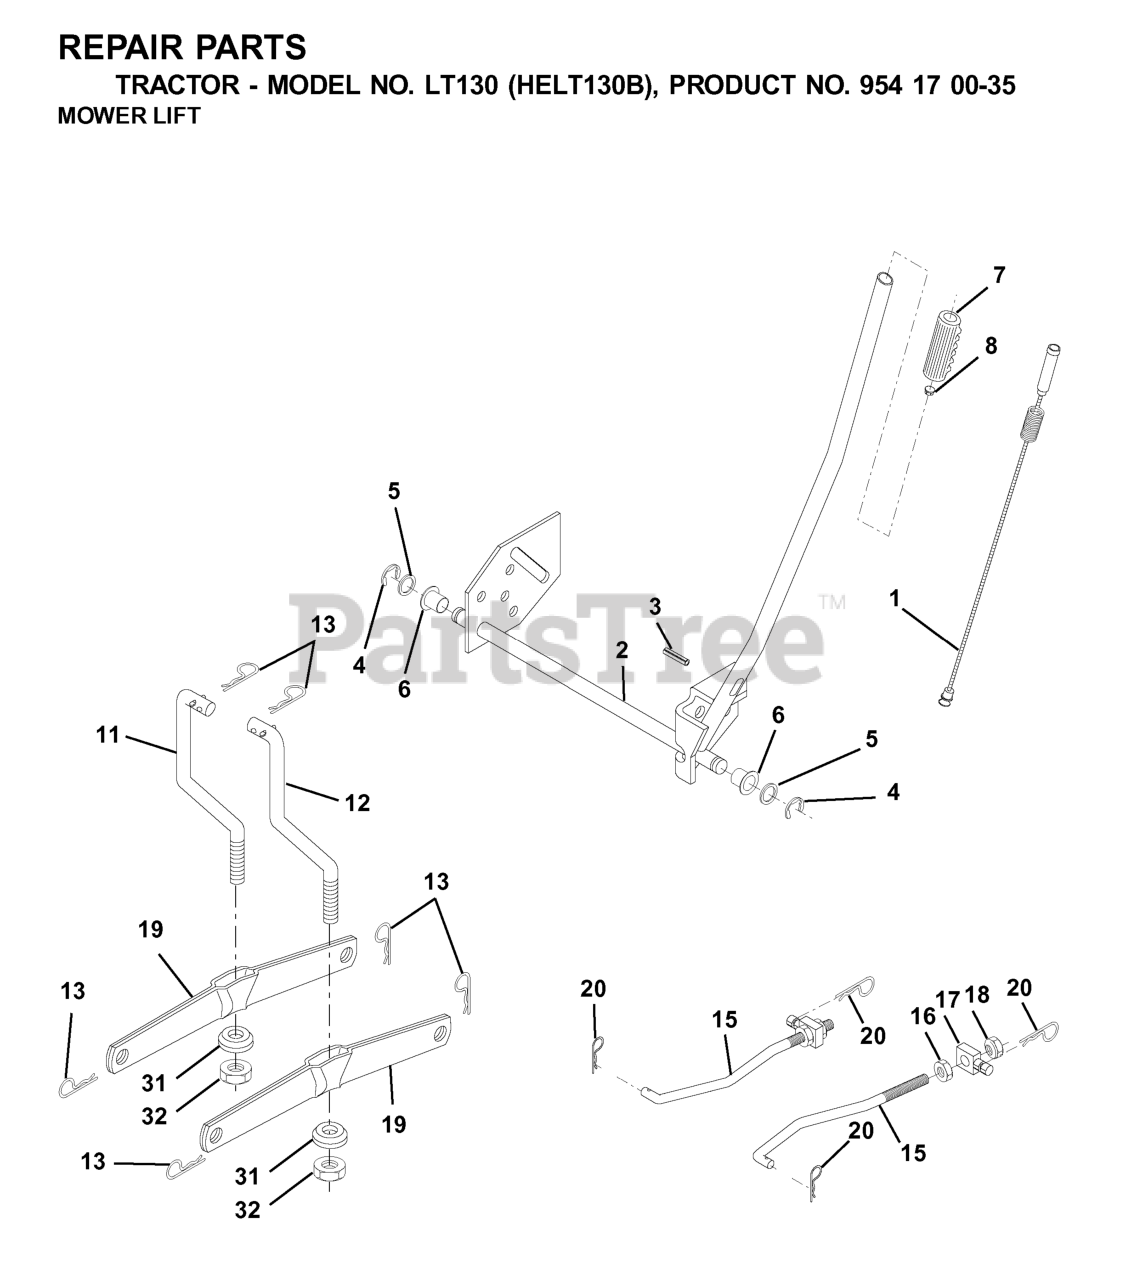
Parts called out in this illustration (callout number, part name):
1	WIRE ASM INNER W/ PLUNGER LT
2	SHAFT ASM R HANDLE
3	PIN GROOVE.
4	RETAINING RING LT
6	BEARING.NYLON
8	PLUNGER BUT KIT
11	LINK LIFT LH
12	LINK LIFT RH
13	RETAINER-SPRNG RB
15	LINK.SUSPENSION.FRONT
16	NUT.HEX.JAM.1/2-13
17	TRUNION
18	NUT.LK.W/WSH.1/2.
19	ARM.REAR.SUSPENSION
20	SPRING RETAINER
31	BEARING.PIVOT.LIFT
32	NUT CROWNLOCK 3/8-24
